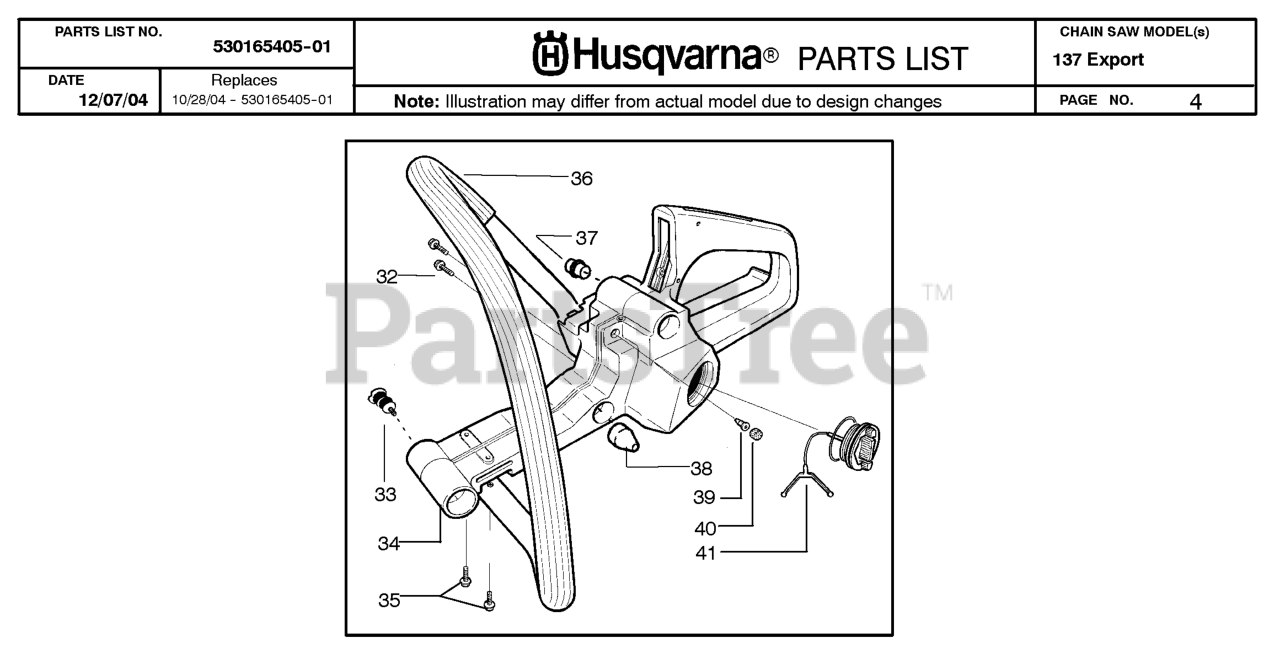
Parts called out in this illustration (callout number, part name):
36	HANDLE FRONT
37	FRONT HANDLE ISOLATOR
38	SHOCK MOUNT(X2) 36/41
39	VALVE-CHECK (DUCKBILL)
40	BRONZE PLUG
41	FUEL CAP KIT
